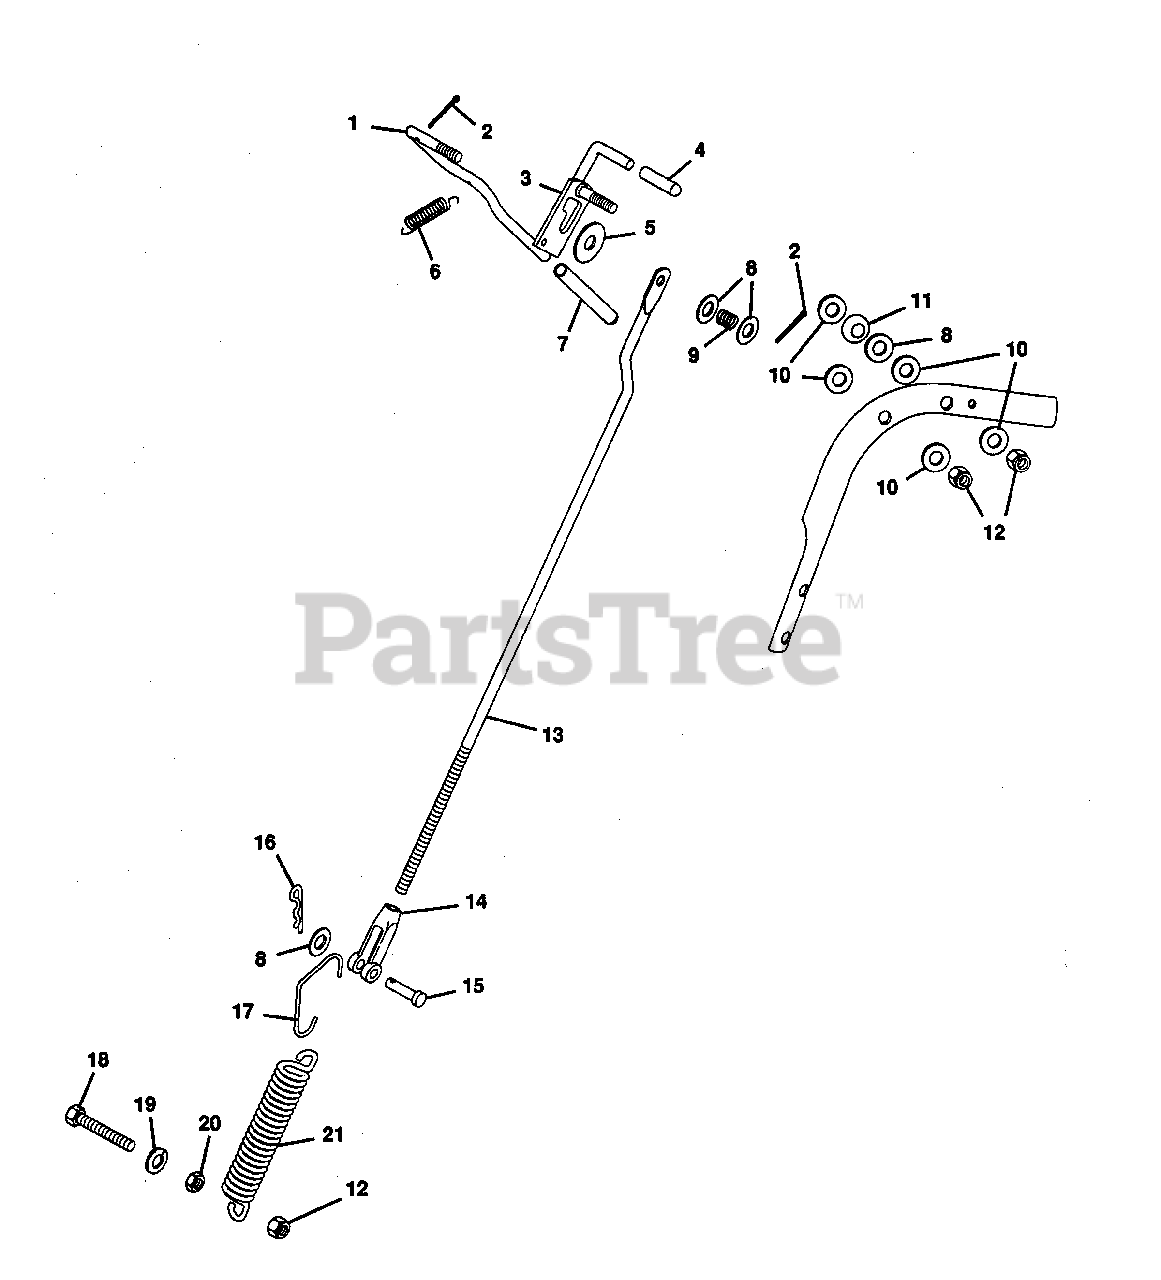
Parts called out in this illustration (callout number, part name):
1	Lever, Hand Control
2	Pin, Cotter .09x.75
3	Weldment, Neutral Lock Lever
4	Tip, Brake Lock Lever
5	Washer, Flat .438x1 .375x.083
6	Spring, Extension
7	Grip, Hand Clutch Lever
8	Washer, Flat .406x.812x.065
9	Spring, Compression
10	Washer, Nylon .375x.75x.06
11	Washer, Spring .375 I.D.
12	Nut, Lock 3/8-16
13	Rod, Steering Control
14	Clevis, 3/8-24 Adjustable
15	Pin, Clevis
16	Pin, Cotter Hair
17	Hook, Spring
18	Bolt, Hex 3/8-16x2.5
19	Washer, Lock 3/8 Reg.
20	Nut, Hex 3/8-16
21	Spring, Ext. LE-105J-7
